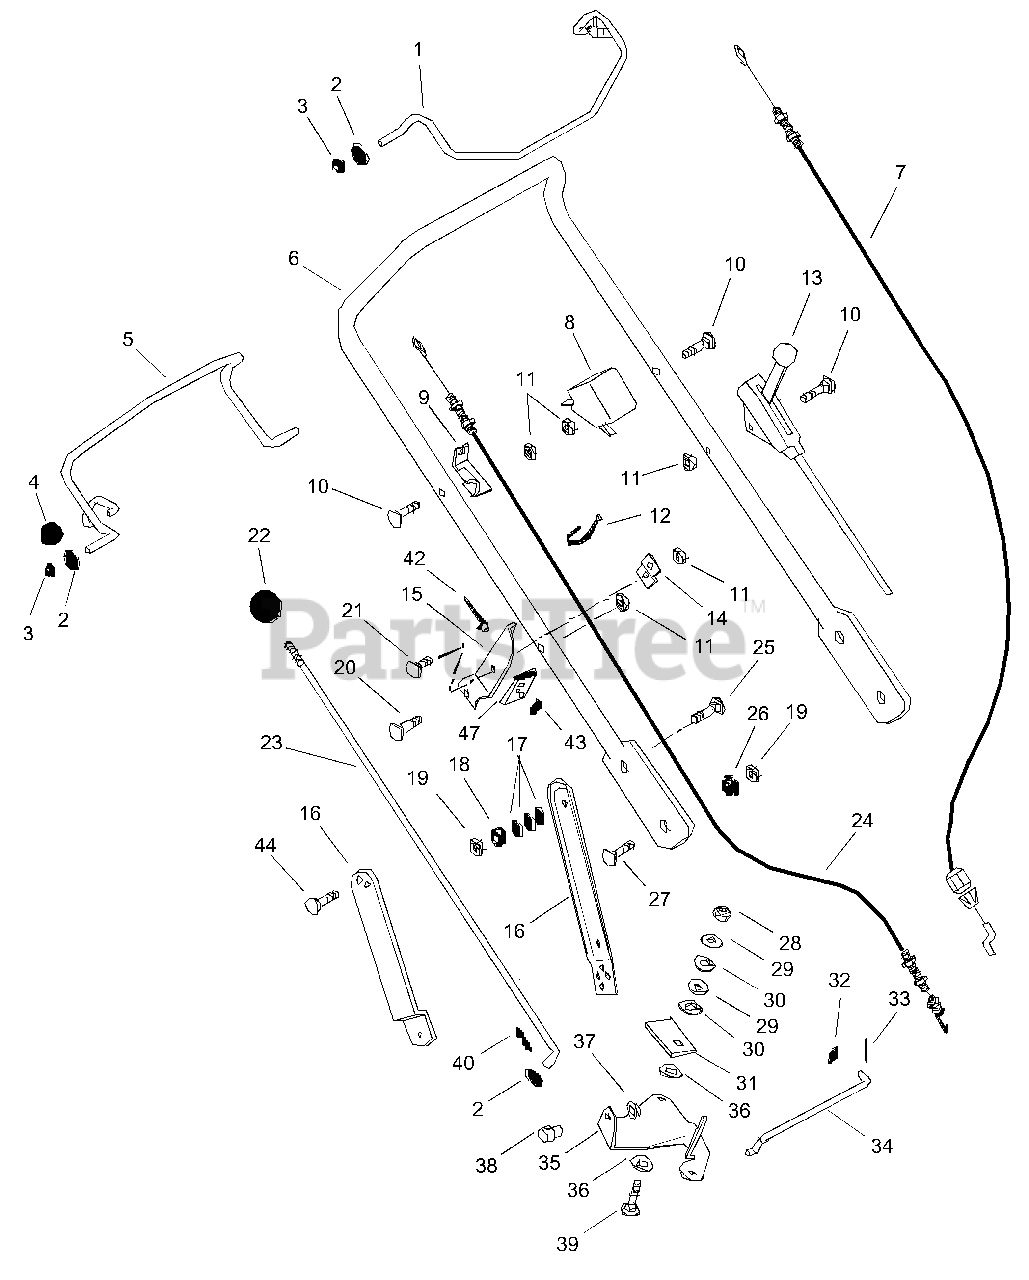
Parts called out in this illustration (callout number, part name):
1	ENGINE BAIL
2	@WSHR-FL-STL.344X.688X.065YWZC
3	BSHG-FLG .325X.444X.440X.560
4	CAP, VINYL, .25 ID
5	TRACTION BAIL
6	HANDLEBAR PUSH
6	HANDLEBAR SELF-PROPELLED
7	ENGINE CONTROL CABLE
7	ENGINE CABLE
8	SWITCH-CABLE ANCHOR
9	CABLE ANCHOR
9	CABLE ANCHOR-LH
10	BLT-RDHDXLSQNK.25-20X1.25 G5ZC
11	@NUT-LK-CTR .25-20 YWZC
12	CABLE TIE LG 5-1/2
13	THROTTLE CABLE
14	BRACE-SPEED CONTROL
15	BRACKET-SPEED CONTROL
16	LINK,HANDLE BAR ADJUST LH
16	LINK,HANDLE BAR ADJ RH
16	HANDLEBAR BRACKET
17	WASHER, BELLEVILLE YWZC
18	BSHG-FLG .325X.500X.513X.875
19	@NUT-LK-CTR .31-18 YWZC
20	@BLT-RDHDSQNK .25-20X1.50 G5YZ
21	@BLT-RDHDSQNK .25-20X.50 G5YZ
22	KNOB, BALL 5/16-18 X 1.5
23	ROD-SPEED CONTROL
24	TRACTION CABLE
25	@BLT-RDHDSQNK .31-18X1.00 G5YZ
26	BSHG, FLG .325X.499X.26X.88
27	@BLT-RDHDSQNK .31-18X.75 G5YZ
28	@NUT-LK-CTR .38-16 YWZC
29	@WSHR-FL-STL.406X.812X.065 YWZ
30	@WSHR-LK .38X.094 REG YWZC
31	PRESSURE FLANGE
32	@WSHR-FL-STL.281X.62X.065 YWZC
33	@PIN-CTR .06X.50 EXTPRSQCT YWZ
34	SHIFT LINK
35	BELL CRANK, SPEED CONTROL
36	FRICTION WASHER
37	CAP, 3/8 ROD YWZC
38	SWIVEL
39	@BLT-RHDSSQNK .38-16X1.25 G5YZ
40	PIN-HAIR INT .08X.18X1.18 YWZC
41	SUPPORT PAD
42	RVT .187X.575 DOME AL BLACK
43	@WSHR-FL-STL.219X.50X.049 YWZC
44	@BLT-HEX .31-18X.75 GR5 YWZC
